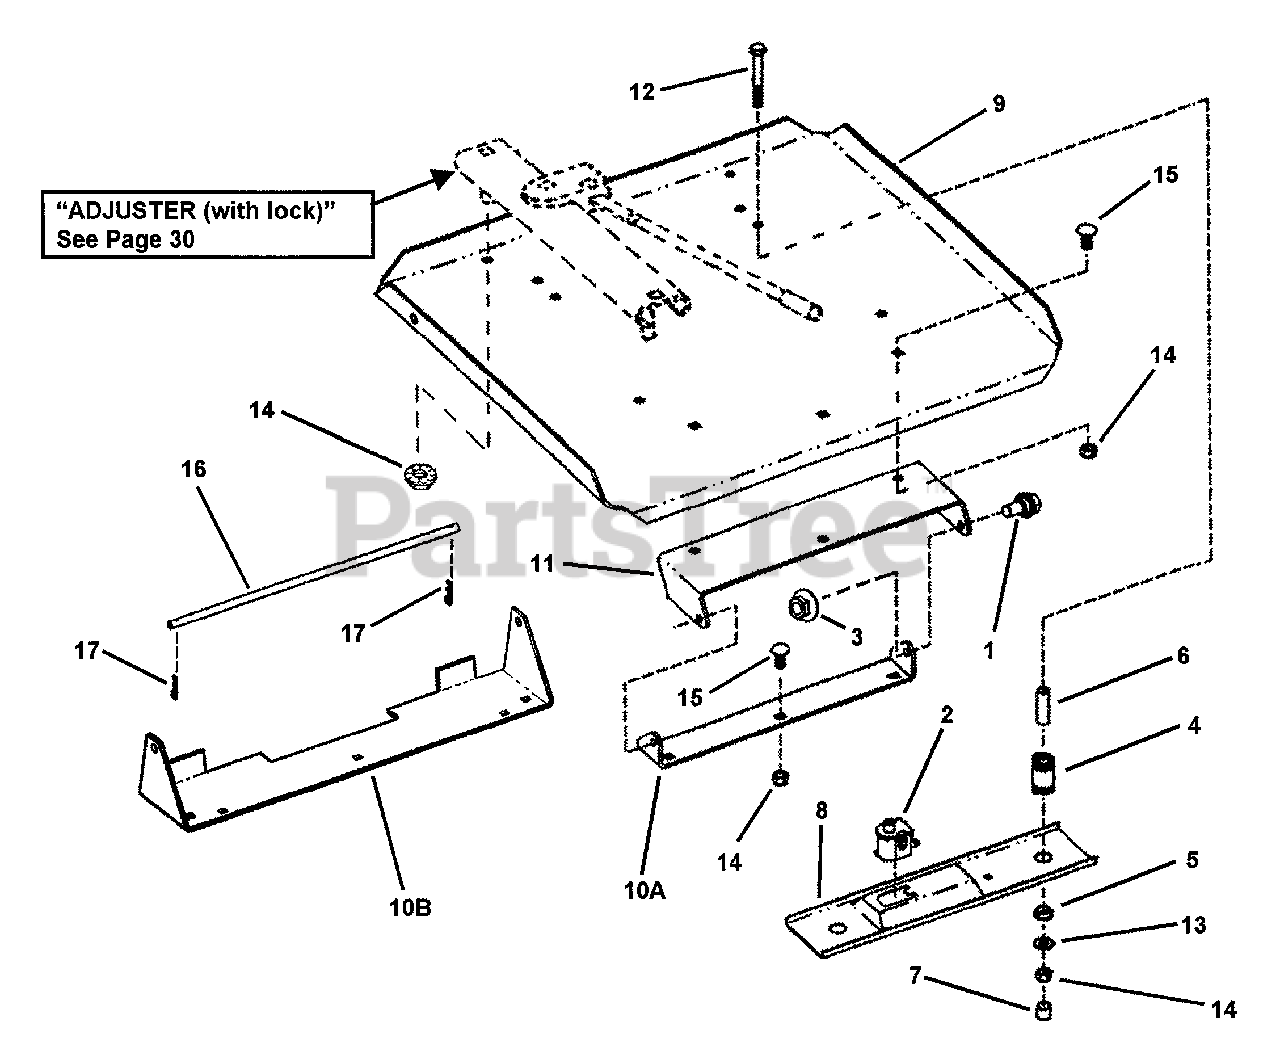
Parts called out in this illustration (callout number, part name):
1	BOLT, 5/16-18 Shoulder
2	SWITCH, Seat
3	NUT, 5/16-18 Hex Center Lock
4	SPRING, .106 Wire Dia., .68 I.D. x 1-1/2"
5	BUSHING, Molded Seat, 1/2 I.D. x 5/8" O.D.
6	SPACER, .31 I.D., 1-3/8" Long
7	CAP, Vinyl, 1/4 I.D. x 1/5 O.D.
8	HOLDER, Seat Switch
9	PLATE, Seat Support
10A	BRACKET, Lower Seat Hinge
10B	BRACKET, Seat Hinge (Model EZF2100DKU)
11	BRACKET, Upper Seat Support Hinge
12	BOLT, 5/16-18 X 2-1/2" GD5 YZ
13	WASHER, 5/16 x 11/16 O.D. Flat
14	NUT, 5/16-18 HEX NYLON LOCK
15	BOLT, 5/16-18 x 3/4 Short Sq. Nk. Carriage, Grade 5
16	ROD, 5/16 x 13" Long
17	HAIRPIN, 3/32 x 1-1/2"
